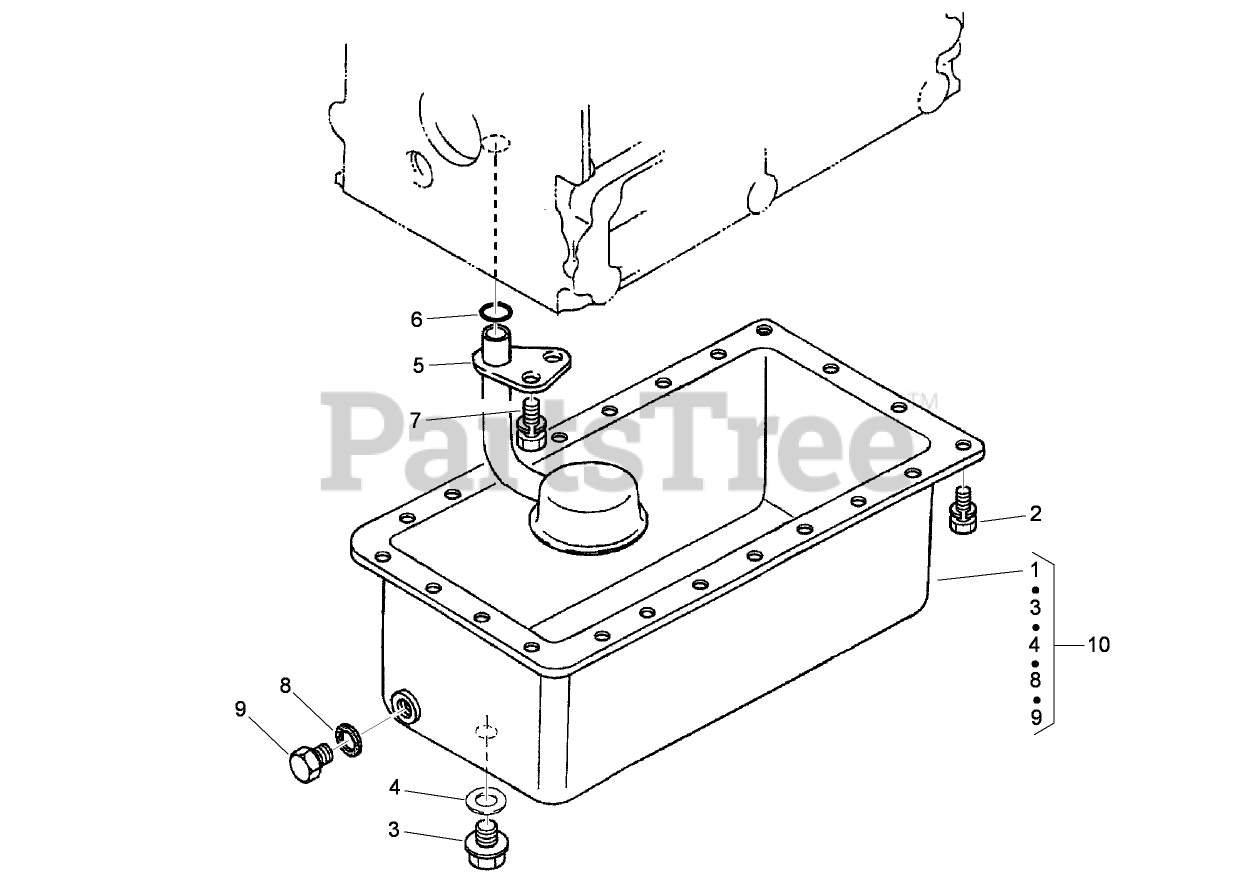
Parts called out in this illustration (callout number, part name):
1	PAN-OIL
2	BOLT
3	PLUG-DRAIN
4	GASKET-PAN, OIL
5	STRAINER-PICKUP, OIL
6	O-RING
8	GASKET
9	PLUG-DRAIN
10	OIL PAN KIT
